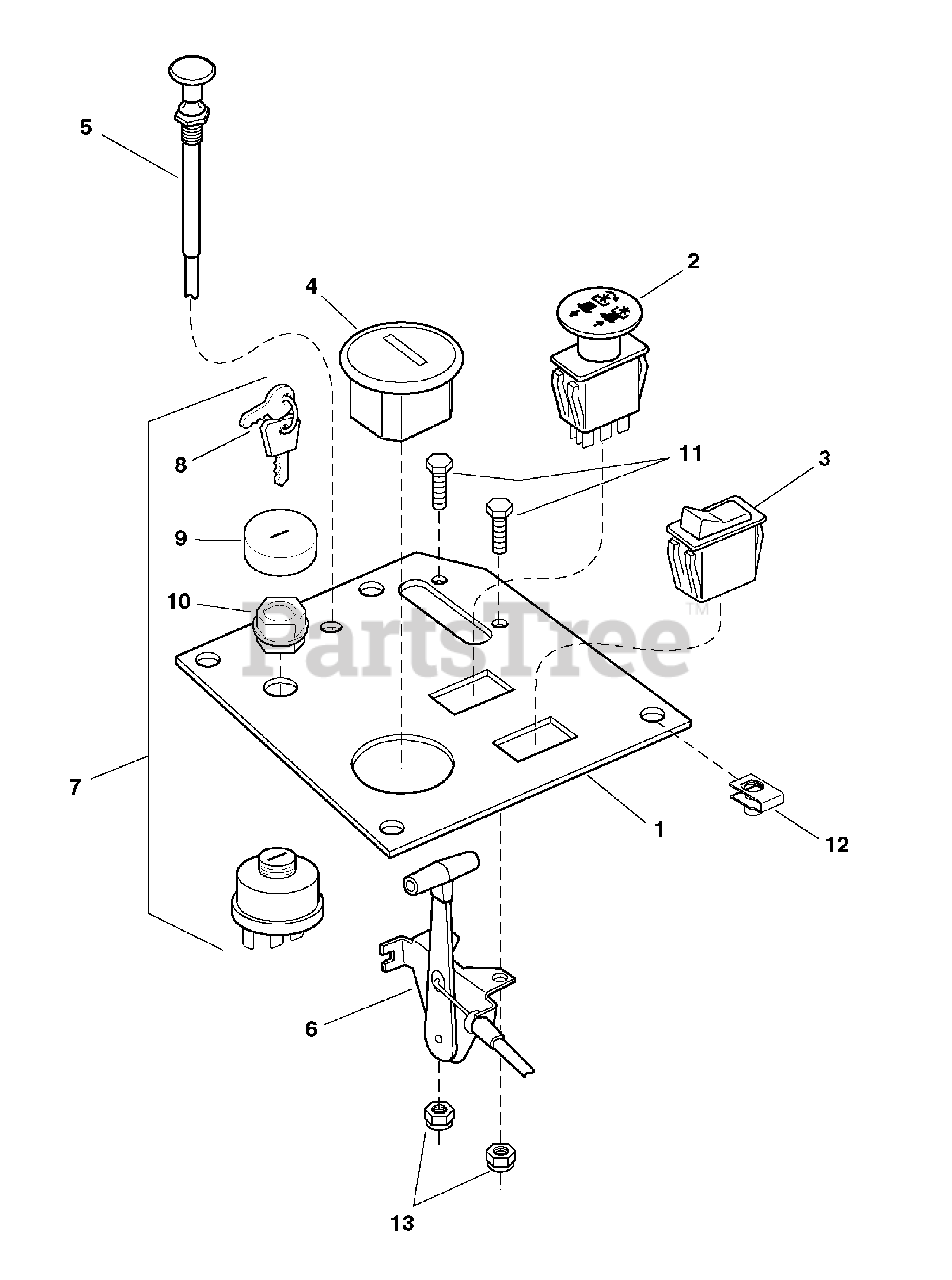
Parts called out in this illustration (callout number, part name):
1	INSTRUMENT PANEL
2	SWITCH, PTO
3	SWITCH, Headlight
5	CABLE, Choke Control (Briggs)
6	CABLE, Throttle Control (Briggs)
7	SWITCH, Ignition, Complete (includes Ref No. 8-10)
8	KEY, Ignition, Molded (Set of 2)
10	PLASTIC NUT
11	CAPSCREW, Hex Hd, 1/4-20 x 3/4
12	BODY CLIP, 5/16-18
13	NUT, Hex, Nylon Lock, 1/4-20
